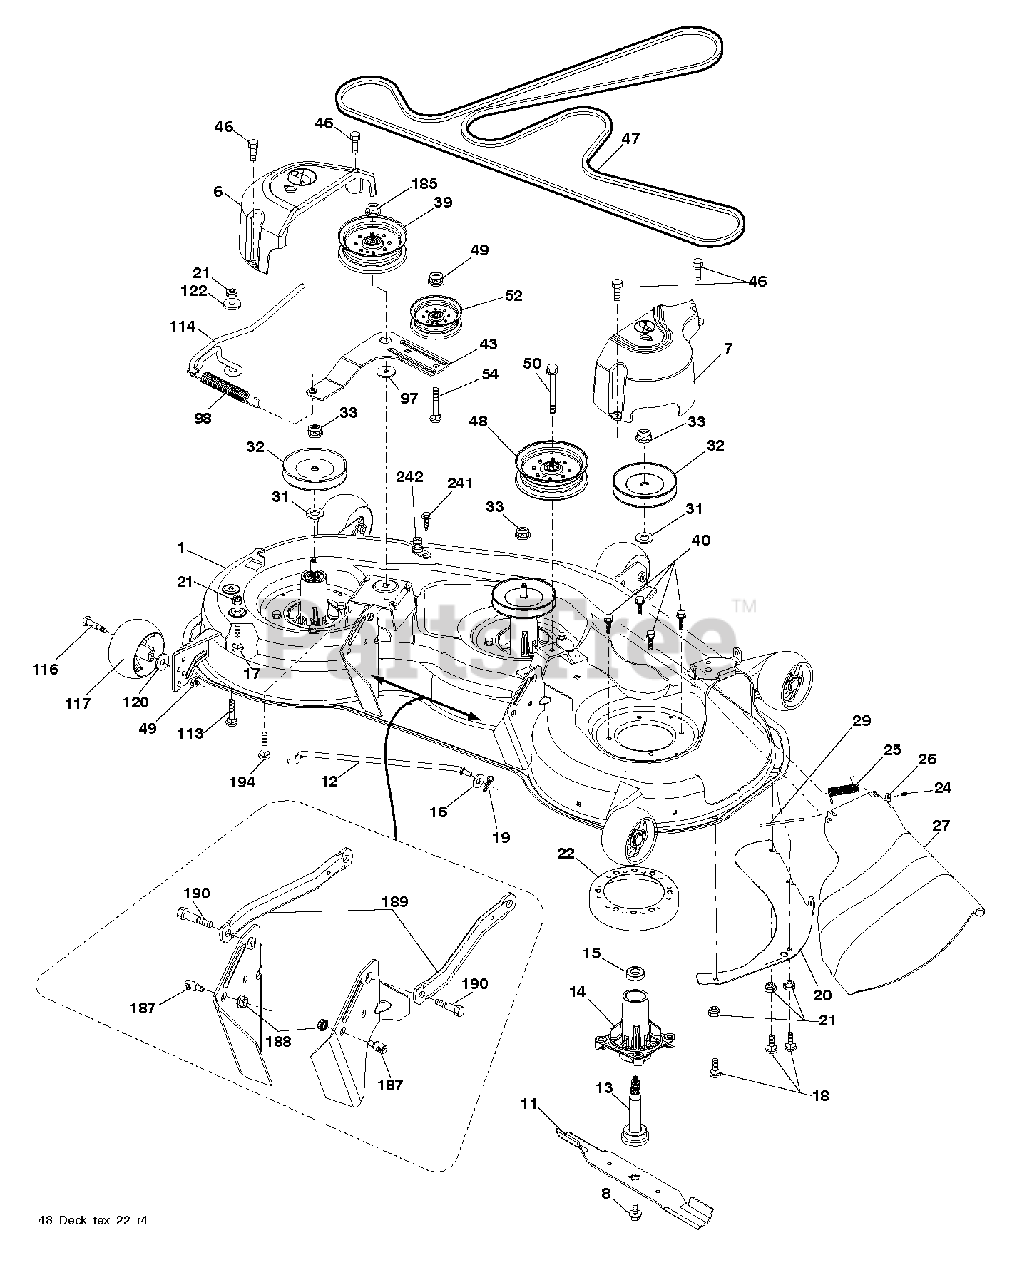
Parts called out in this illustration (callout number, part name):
1	DECK.WELDMENT.48".4GWB.BLUE
6	COVER.MANDREL.LH.48"
7	COVER.MANDREL.RH.48"
8	BOLT.WASHER.ASM.7/16-2
11	48" HI-LIFT BLADE
12	ROD.ANTI.SWAY.48/54"K4
13	SHAFT ASM MANDREL
14	HOUSING.MANDREL.4PT.
15	BEARING
16	WASHER
17	BOLT
18	BOLT
19	PIN.COTTER.5/16.BOW TI
20	BAFFLE, VORTEX MWR
21	LOCKNUT
22	STRIPPER.MANDREL.ROUND.BLACK
24	CAP-SLEEVE LT
25	SPRING, TORSION
26	NUT PUSH M
29	ROD.HINGE
31	WASHER.SPACER.MANDREL
32	PULLEY MANDREL
33	NUT.FLANGE.LOCK.TOP
39	PULLEY.IDLER.4.50/HUB SPECIAL
40	BOLT.HEX.WASHR.HED.313-18X1.19
43	ARM.IDLER
46	SCREW.1/4-20X5/8
47	BELT.DRIVE.DECK
48	PULLEY.IDLER.2006
49	NUT LOCK FLG 3/8-16 UNC
50	SCREW TT 3/8-16X2-1/4 UNC
52	PULLEY.IDLER.48"PRIMARY
54	BOLT.3/8-16X1.50
98	SPRING, DECK DRIVE
113	BOLT CRT
114	ROD.TENSION.RELIEF.TEX (2 2)
116	BOLT.SHOULDER.3/8-16X3-5/8.
117	WHEEL. GUAGE RALLY
120	WASHER
122	BUSHING.RELIEF.TENSION
185	NUT.LOCK.FLANGE.7/16
187	STUD.FASTNER.W/ANTI-ROTATE
188	NUT LOCK HEX FLANGE 5/16-18
189	ARM.SUSPENSION.MOWER
190	BOLT.SHOULDER
194	BOLT.HEX.WASHER.HEAD.7/16-24X
241	SCREW.TT.#10-32X.5.3/8.FLANGE
242	PORT.WASHOUT
